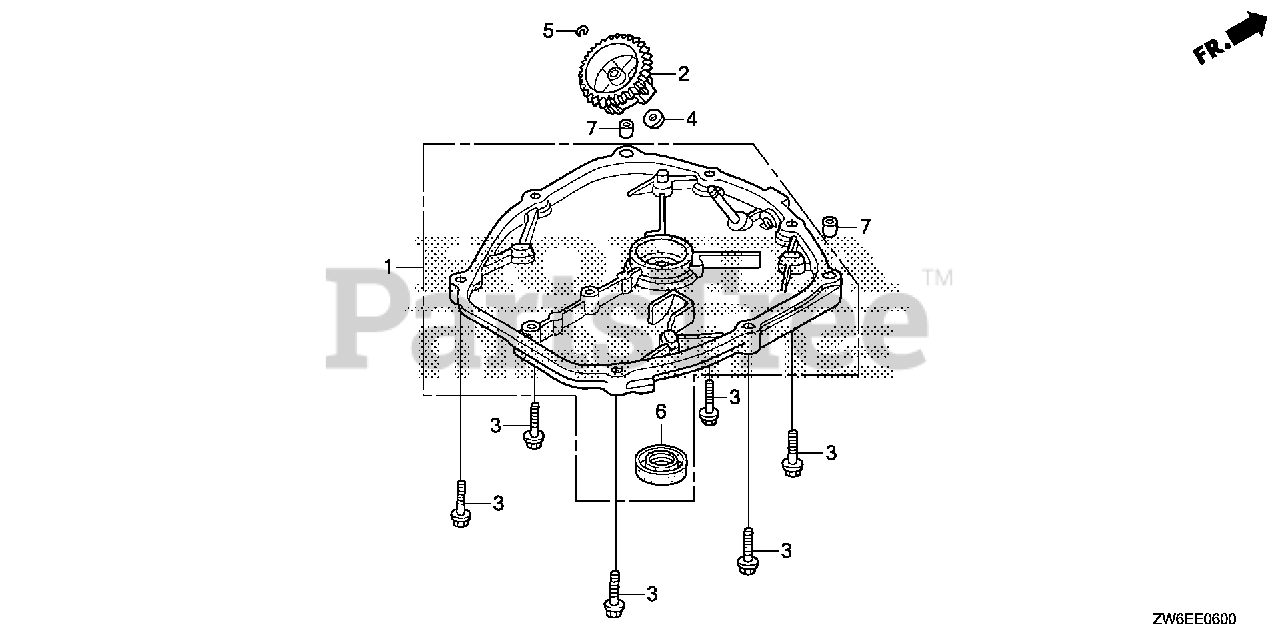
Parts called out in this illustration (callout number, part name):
1	COVER, CRANKCASE SIDE
2	HOLDER, GOVERNOR WEIGHT
3	BOLT, FLANGE (5X23) (CT200)
4	WASHER (4.2X13)
5	CLIP, GOVERNOR HOLDER
6	OIL SEAL (17X27X5) (KOYO)
7	PIN, DOWEL (6X10)
